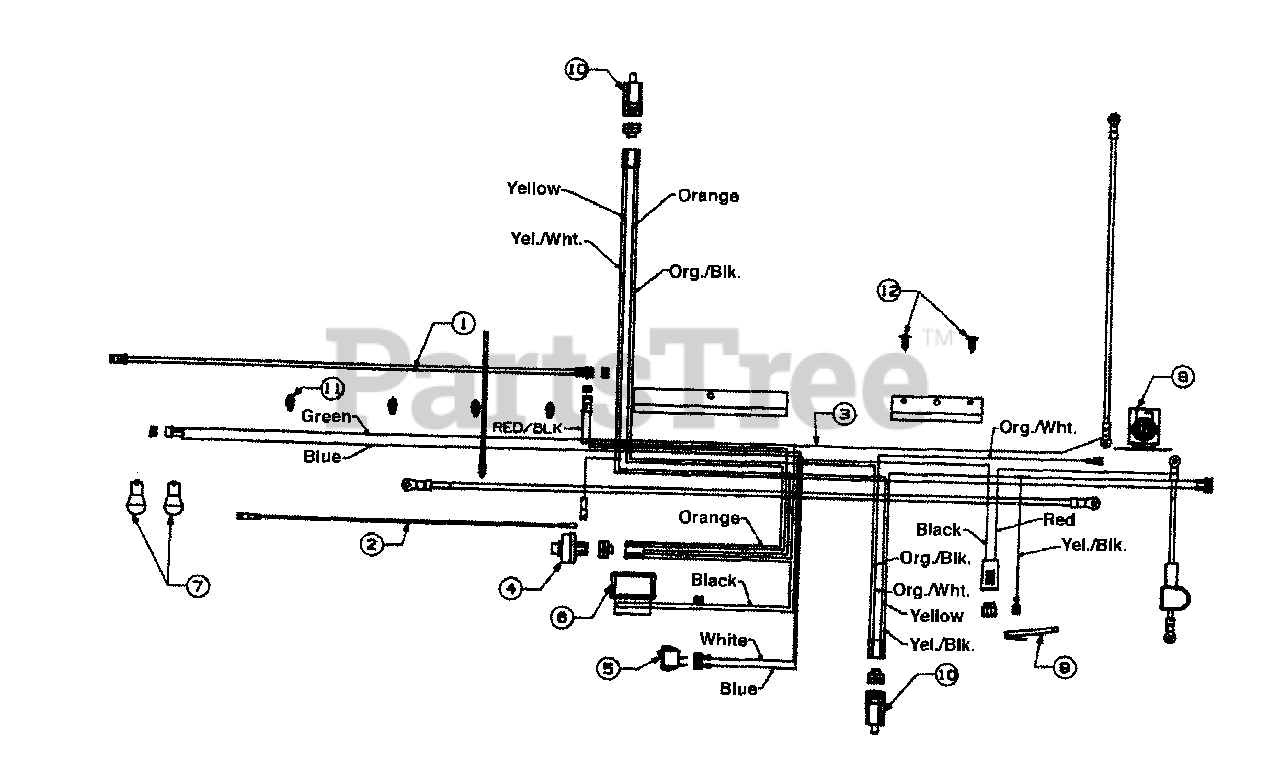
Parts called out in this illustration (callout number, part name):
1	Harness Adapter (Alt.)
2	Harness Adapter
3	Wire Harness w/Light Switch & Amp
4	Ignition Switch
5	Light Switch
6	Ammeter
7	Bulb
8	Solenoid
9	Safety Switch (Reverse)
10	Safety Switch
11	Wire Retainer Clip
12	Ratchet
